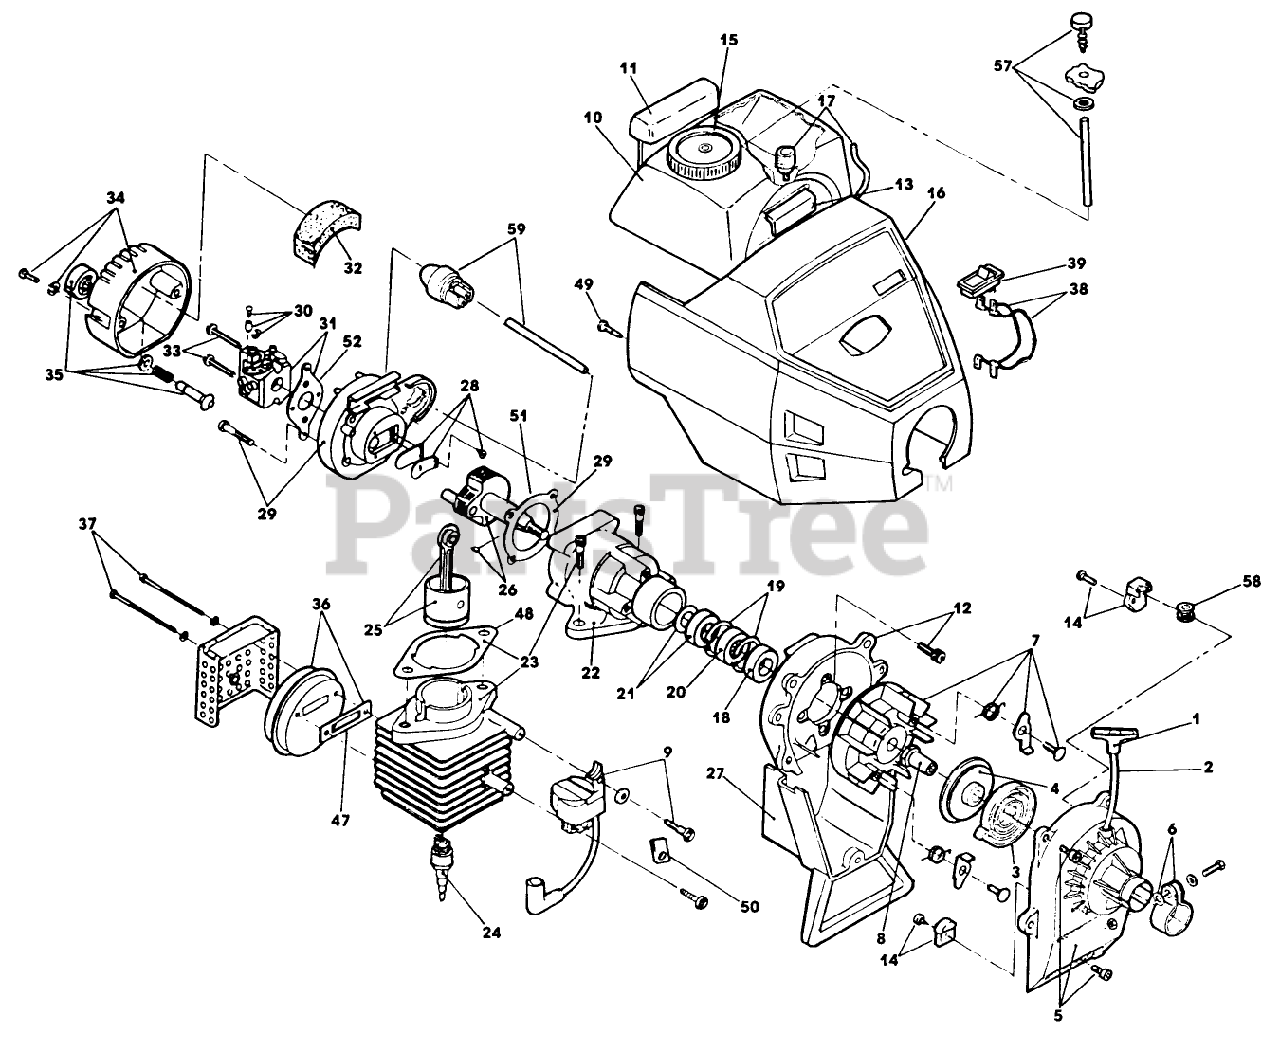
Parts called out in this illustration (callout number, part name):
3	RECOIL SPRING
8	SQUARE DRIVE NUT
11	REAR MOUNTING PAD
12	SHROUD ASM
13	FRONT MOUNTING PAD
17	FUEL LINE ASM
18	OUTER BEARING
21	INNER BEARING ASM
24	SPARK PLUG
30	THROTTLE ADJ ASM
37	MTNG BOLT ASM 2 PCS = 1
52	CARB.GASKET
57	FUEL RETURN LINE ASM
